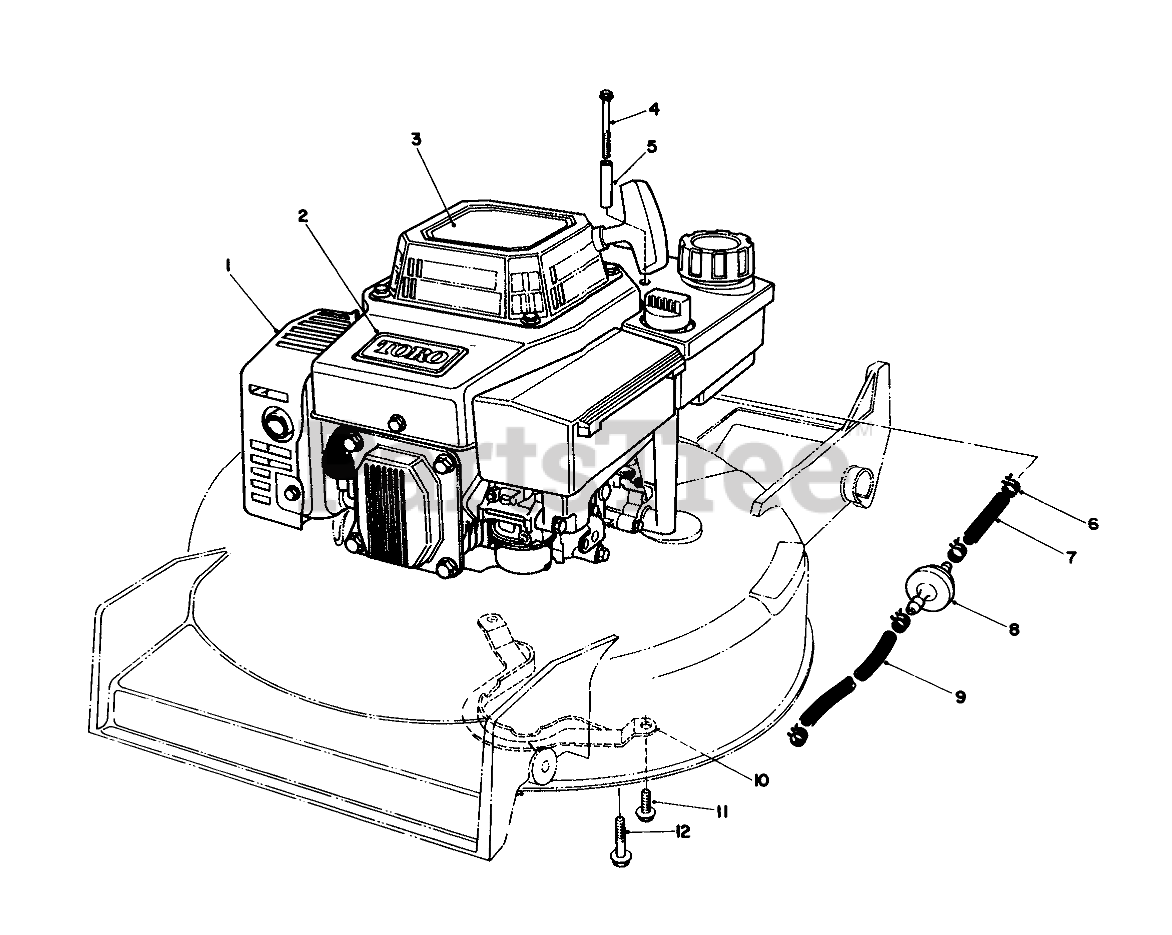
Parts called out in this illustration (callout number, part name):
1	Engine
2	TORO LOGO PLT
3	DECAL-HV INT'L
4	THRD FORMING SCREW
5	TUBULAR SPACER
6	CLAMP-FUEL LINE
7	LINE-GAS
8	FILTER-FUEL
9	HOSE-FUEL
10	BBC BELT GUIDE
11	SCREW-HWHTF
12	SCREW-HWHTF
